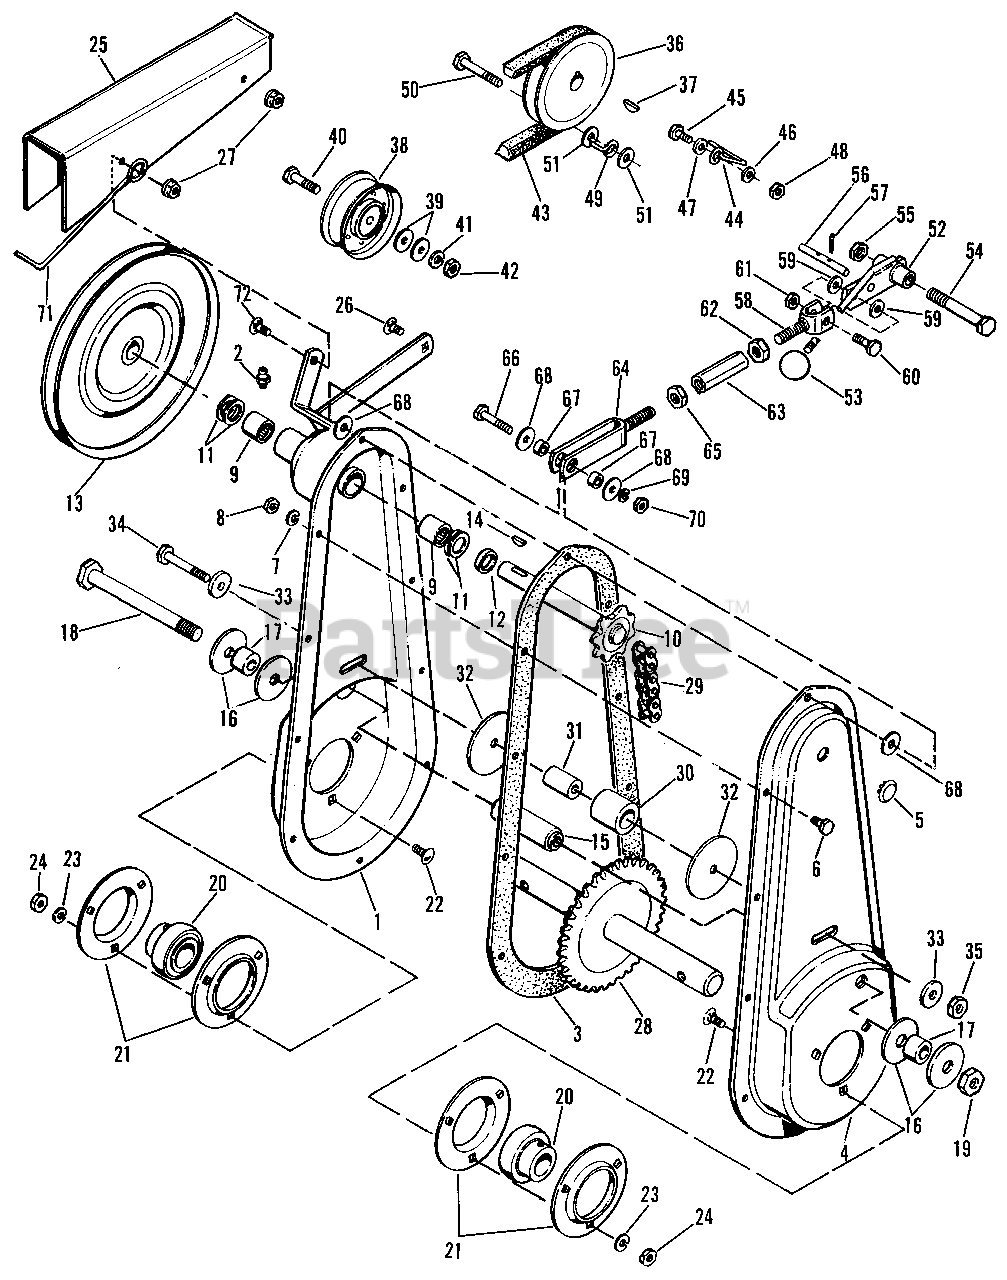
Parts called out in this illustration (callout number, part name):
1	L.H. Case Assembly
2	Grease Fitting
3	Case Gasket
4	R.H. Case Assembly
5	Plug Button
6	Hex Capscrew, 5/16"-18 x 5/8" lg.
7	Lock Washer, 5/16"
8	Hex. Full Lock Nut, 5/16"-18
9	Needle Bearing
10	Drive Shaft Assembly
13	Pulley (Driven)
14	Woodruff Key, 3/16" x 3/4"
15	Case Spacer
18	Hex Capscrew, 1/2"-13 x 5-1/2" lg.
19	Hex Nut, Full, Lock, 1/2"-13
21	Bearing Flange
22	Carriage Bolt, 5/16"-18 x 3/4" lg.
23	Lock Washer, 5/16"
24	Hex Nut, Full, 5/16"-18
25	Belt Guard
26	Carriage Bolt, Short Sq. Neck 5/16"-18 x 1/2"
27	Special Nut, 5/16"-18
28	Tine Shaft Assy.
34	Hex Capscrew, 3/8"-16 x 2-1/4" lg.
35	Hex Nut, Full, Lock, 3/8"-16
36	Pulley (Driver)
37	Woodruff Key, 3/16"-3/4"
38	Idler Pulley
39	Plain Washer, 5/16"
40	Hex Capscrew, 3/8"-16 x 1-1/4" lg.
41	Lockwasher, 3/8"
42	Hex Nut, Full, 3/8"-16
43	"V" Belt
44	Belt Stop
45	Hex Capscrew, 5/16"-18 x 3/4" lg.
46	Lock Washer, 5/16"
47	Plain Washer, 1/4"
48	Hex Nut, Full, Lock, 5/16"-18
50	Hex Capscrew, 3/8"-16 x 1-3/4" lg.
51	Plain Washer, 5/16"
52	Clutch Lever Assembly
54	Hex Capscrew, 7/16"-14 x 2-3/4"
55	Hex Nut, Full, Lock 7/16"-14
57	Cotter Pin, 3/32" x 3/4"
58	L.H. Clevis Assembly
60	Hex Capscrew, 5/16"-18 x 1" lg.
61	Hex Nut, Full, Lock, 5/16"-18
62	Hex Nut, Full, 7/16"-14 L.H. Thread
63	Turnbuckle
64	R.H. Yoke Assembly
65	Hex Nut, Full 7/16"-14
66	Hex Capscrew, 5/16"-18 x 1-1/2" lg.
68	Plain Washer
69	Lock Washer
70	Hex Nut, Full, 5/16"-18
71	Belt Stop
72	Carriage Bolt, 5/16"-18 x 3/4" lg.
